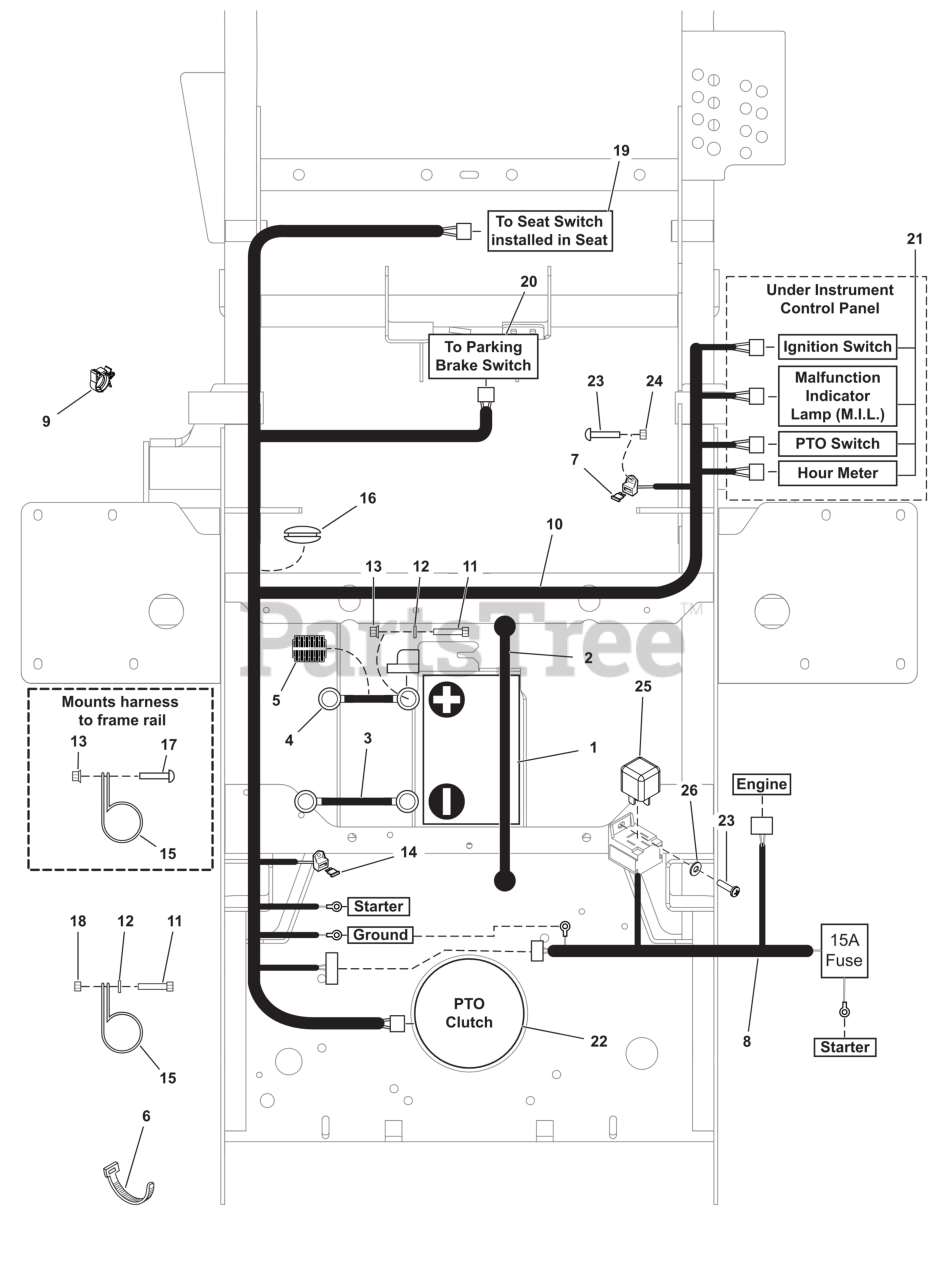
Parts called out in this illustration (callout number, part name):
1	BATTERY, 11U1L, 350 CCA
2	STRAP
3	BATTERY CABLE, NEGATI
4	BATTERY CABLE, POSITI
6	TIE WRAP, 11" Long
7	FUSE
8	HARNESS, Wiring
10	HARNESS-WIRING
11	BOLT, 1/4-20 X 3/4" G
12	WASHER
14	FUSE, ATO 15 AMP
16	GROMMET, 1-1/2" ID FOR 1/4" METAL
19	Refer to: Seat Mount & Floor Group
20	Refer to: Parking Brake Group
21	Refer to: Instrument Control Panel Group
22	Refer to: Engine & PTO Group
23	SCREW - #10-24
25	RELAY, 12V, 40A
26	WASHER, #10 SAE
